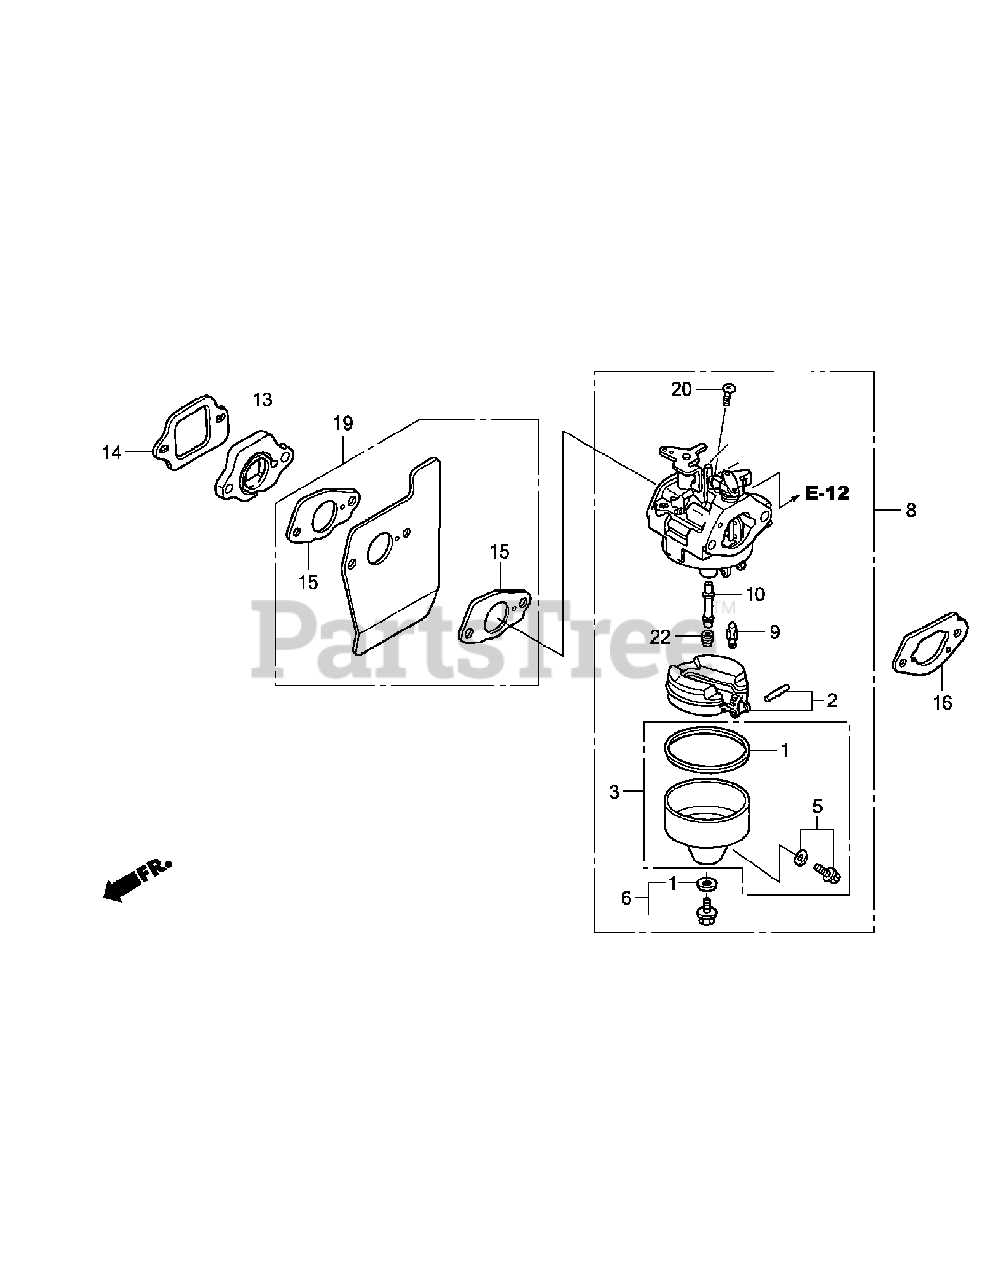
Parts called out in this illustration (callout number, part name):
1	Gasket Set.
3	Chamber Set, Float
5	Screw Set, Drain
6	Screw Set
8	Carburetor Assy..
9	Valve, Float
10	Nozzle, Main
13	Insulator, Carburetor
14	Gasket, Insulator
15	Gasket, Carburetor
16	Gasket, Carburetor
19	Guide, Air
20	Screw, Pan (5x6)
22	Jet, Main (#60)
22	Jet, Main (#62)
22	Jet, Main (#65)
